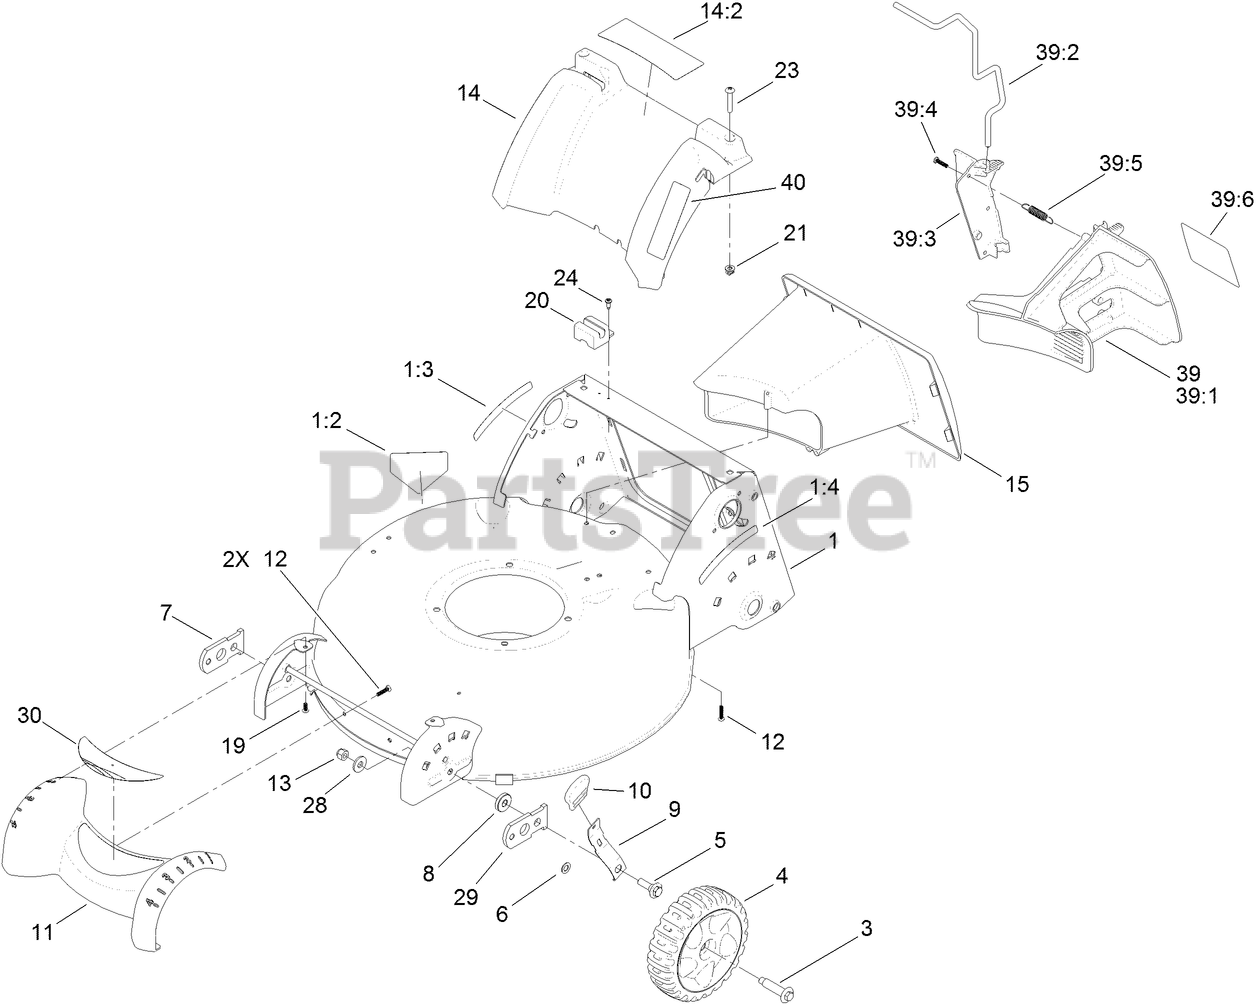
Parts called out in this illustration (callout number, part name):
1	53CM DECK BAFFLE ASM
1:2	DECAL-DANGER
1:3	DECAL-HOC, RH
1:4	DECAL-HOC, LH
3	BOLT-SHOULDER
4	7 INCH WHEEL AND TIRE ASM
5	SCREW-SHOULDER, HWH
7	ARM-PIVOT, RH
9	ARM-SPRING
11	COVER-FRONT
12	SCREW-PLASTITE
13	NUT-LOCK, NI
14	REAR COVER ASM
14:2	DECAL-WARNING
19	SCREW-PLASTITE
20	MODULE-SWITCH
21	NUT-CLIP
23	SCREW-PTH
24	SCREW-FORMING, THREAD
28	WASHER-HARDENED
29	ARM-PIVOT, LH
30	DECAL-LOGO
39	MULCH PLUG ASM
39:1	PLUG-MULCH, LH
39:2	LATCH-PLUG, MULCH
39:3	PLUG-MULCH, RH
39:4	SCREW-PLASTITE
39:5	SPRING-EXTENSION
39:6	DECAL-PLUG, MULCH
